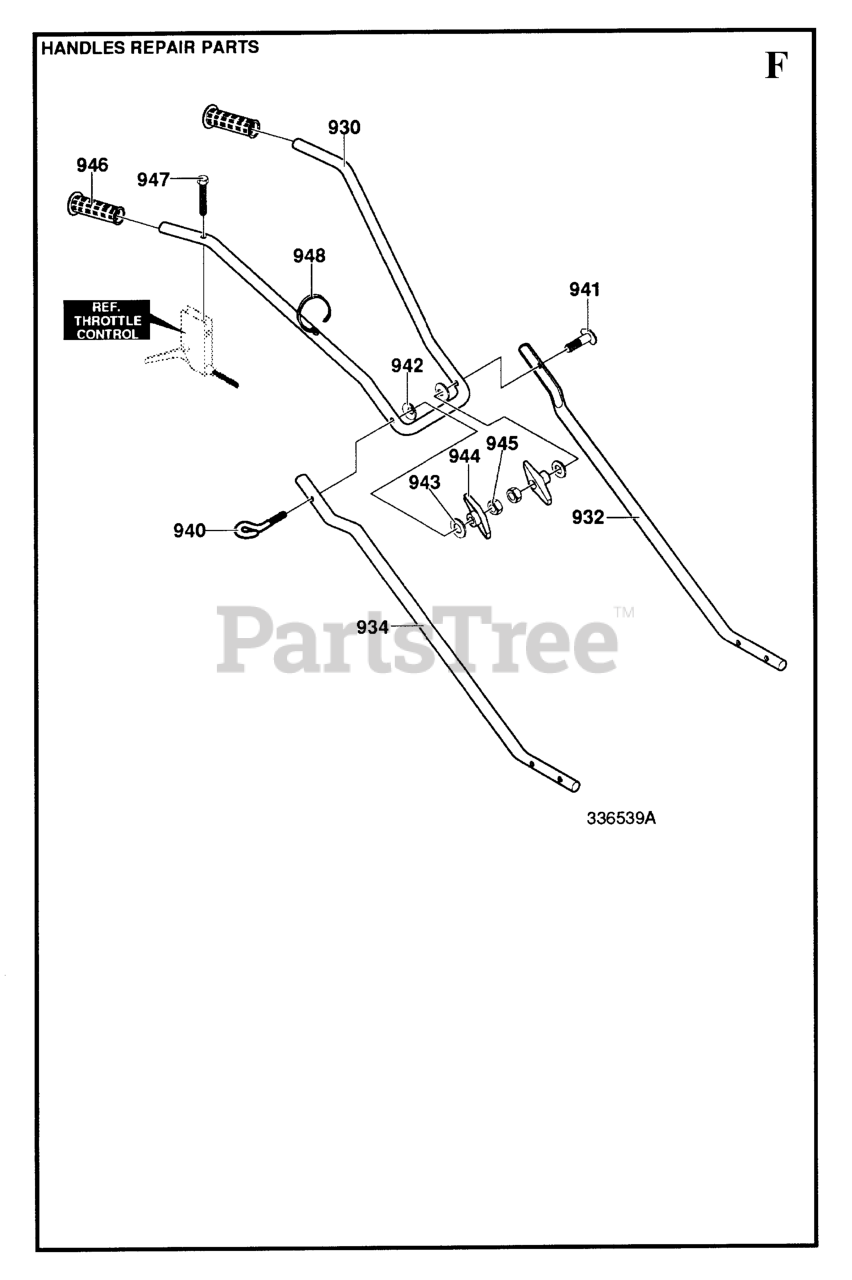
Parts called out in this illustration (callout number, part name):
943	WASHER - 15X7.3X1.6
947	SCREW
948	TIE,CABLE
